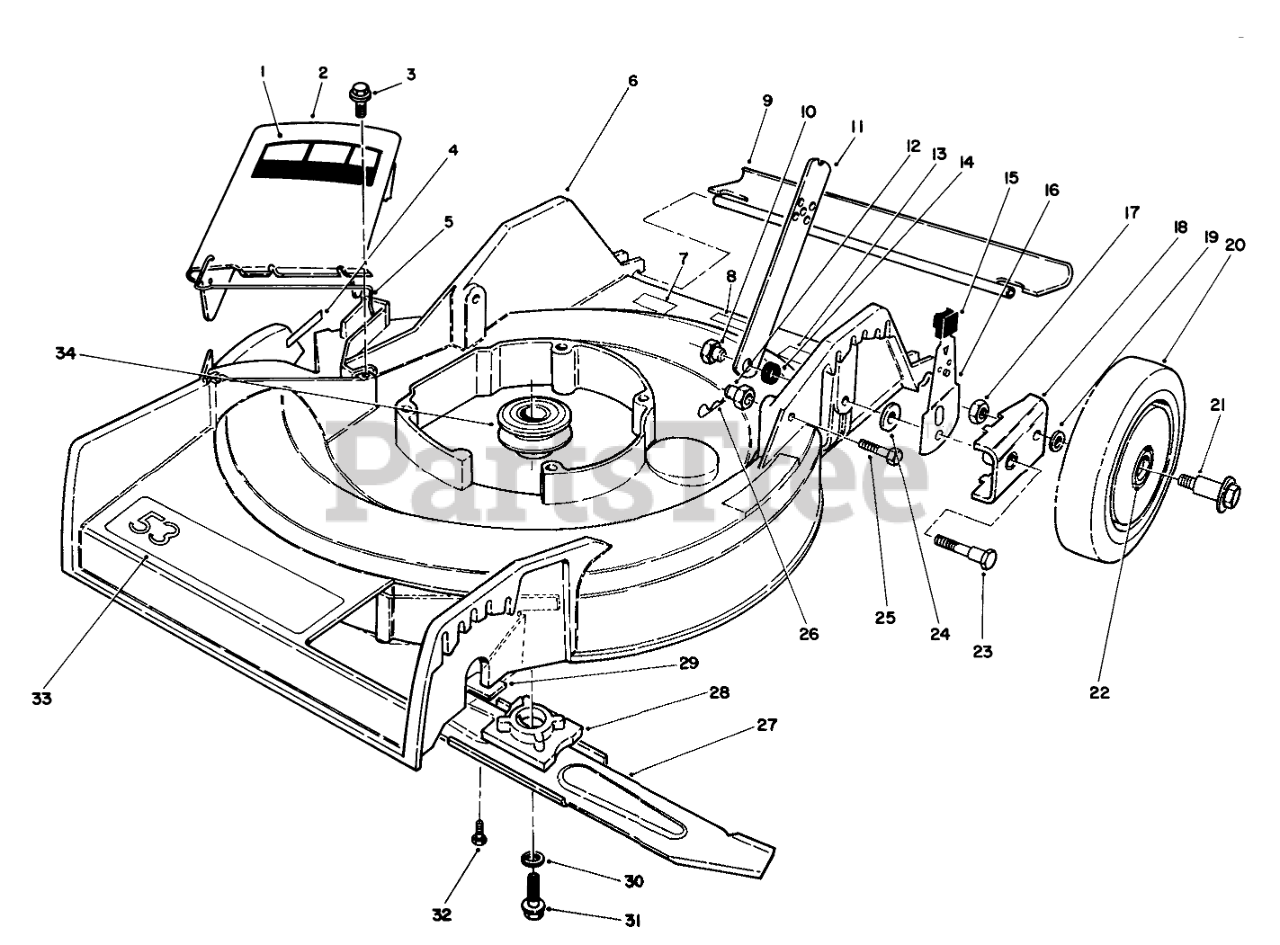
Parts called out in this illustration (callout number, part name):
1	DECAL - DANGER DEFL
2	Deflector (Incl. Ref. #1 & 5)
3	SCREW-HWH
4	DANGER DECAL
5	SPRING HINGE
6	Housing (Incl. Ref. #4)
7	Decal-TUV GS
8	Decal-Power Rating
9	SHIELD - TRAILING
10	HANDLE PIVOT NUT
11	HANDLE LATCH
12	HANDLE PIVOT NUT
13	Decal-Noise Rating
14	SPACER
15	KNOB-ARM
16	SPRING ARM ASSEMBLY
17	Nut
18	HP PIVOT ARM ASM
19	WASHER
20	Wheel & Tire Assembly (Incl. Ref. #22)
21	BOLT-WHEEL
22	BUSHING
23	PIVOT SCREW
24	PIVOT WASHER
25	SCREW-HH
26	PIN-COTTER, HAIR
27	Blade
28	BLADE RETAINER
29	FRONT SHIELD
30	WASHER-LOCK
31	SCREW-HH
32	SCREW-HWHTF
33	DECAL - SP DECK
34	PULLEY-DRIVER
